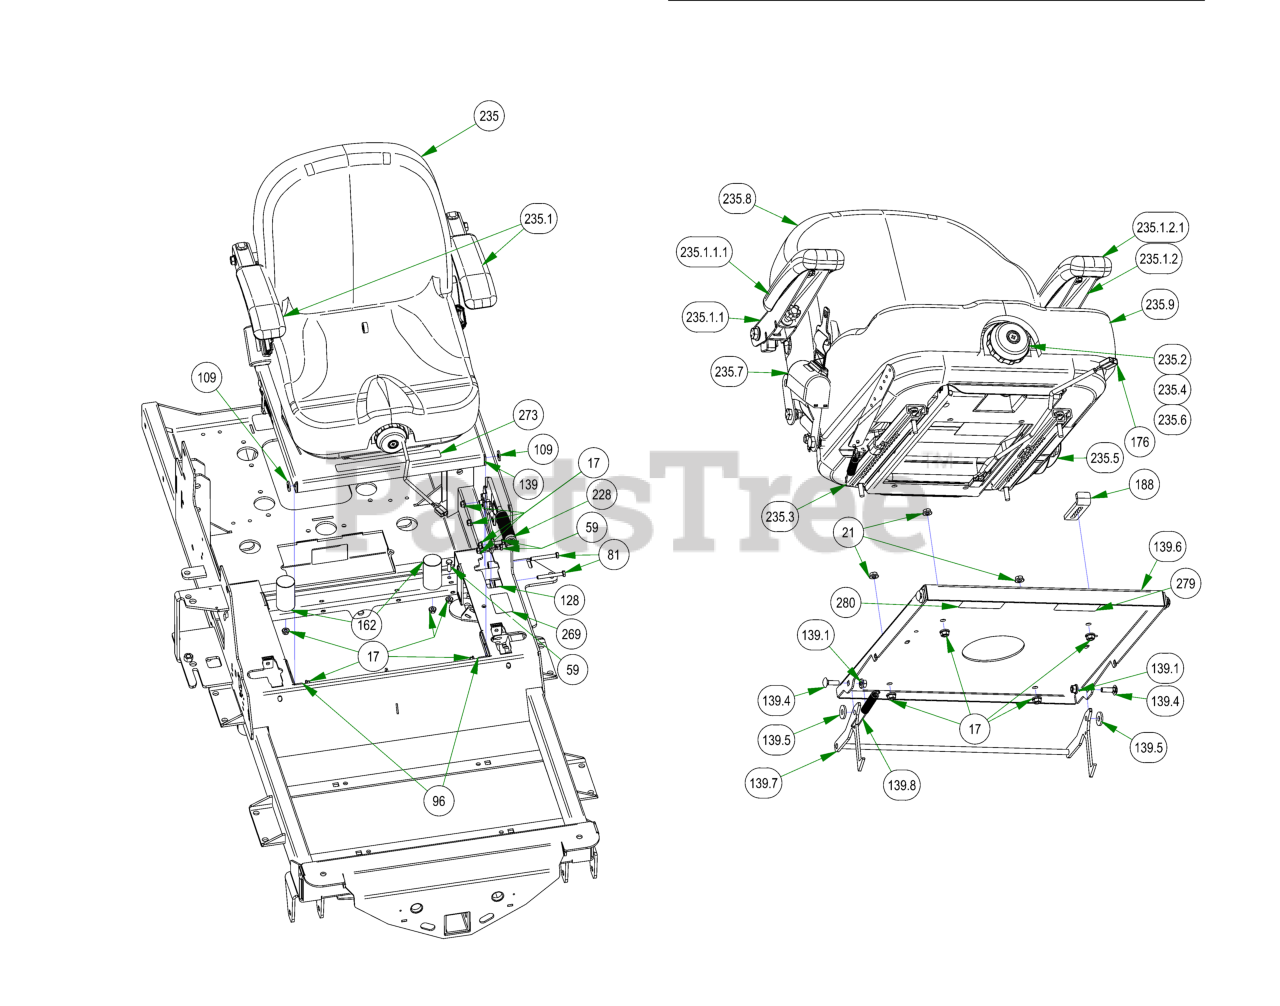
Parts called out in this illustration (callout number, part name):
17	5/16-18 NYLON INSERT FLANGE LOCKNUT ZINC
21	5/16-18 HEX SERRATED FLANGE NUT HARD/ZINC
59	5/16-18 X 1 HEX CAP SCREW (GR.5) ZINC
81	5/16-18 X 2-1/2 HEX CAP SCREW (GR.5) ZINC
96	5/16-18 X 1 CARRIAGE BOLT (GR.8) ZINC
109	.360 ID X .983 OD X .120 THICK FLAT WASHER NYLON
128	.380 ID X .625 OD X 1.500 LGTH 2019 OUTLAW BRAKE HANDLE SPACER ZINC
139	R-SERIES SEAT PLATE ASSEMBLY
139.1	5/16-18 NYLON INSERT FLANGE LOCKNUT ZINC
139.4	5/16-18 X 1 CARRIAGE BOLT (GR.8) ZINC
139.5	.360 ID X .983 OD X .120 THICK FLAT WASHER NYLON
139.6	R-SERIES SEAT PLATE
139.7	Seat Latch Rod Assembly
139.8	Brake Spring
162	2019 Bad Boy X Cylindrical Seat Mount
176	Seat Switch Adapter
228	2019 Brake Handle Assembly
234	2022 Horizontal Diesel Frame
235	2022 Suspension Seat w/Seatbelt
235.1	Set of Armrests-SS Front Adj
235.1.1	RH Armrest-Selfskin Front Adj
235.1.1.1	Black Selfskin-Arm Pad Only
235.1.2	LH Armrest-Selfskin Front Adj
235.1.2.1	Black Selfskin-Arm Pad Only
235.2	Weight Adjust Indicator Knob Assy
235.3	4" Single Locking Track Kit
235.4	Delta Plunger Switch - N.O.
235.5	Recliner Adjustment Knob-New
235.6	Bellows w/Hardware
235.7	2" Retractable Belt Kit w/Spacers
235.8	Back Cover for I3M - Recl - Logos
235.9	Cushion Cover Kit for I3M-Logo
269	2018 Out/XP/Diesel Brake Decal
273	Outlaw Warning Decal
279	Control Adj. Control Rod Decal
280	Control Adj. Control Dampener Decal
